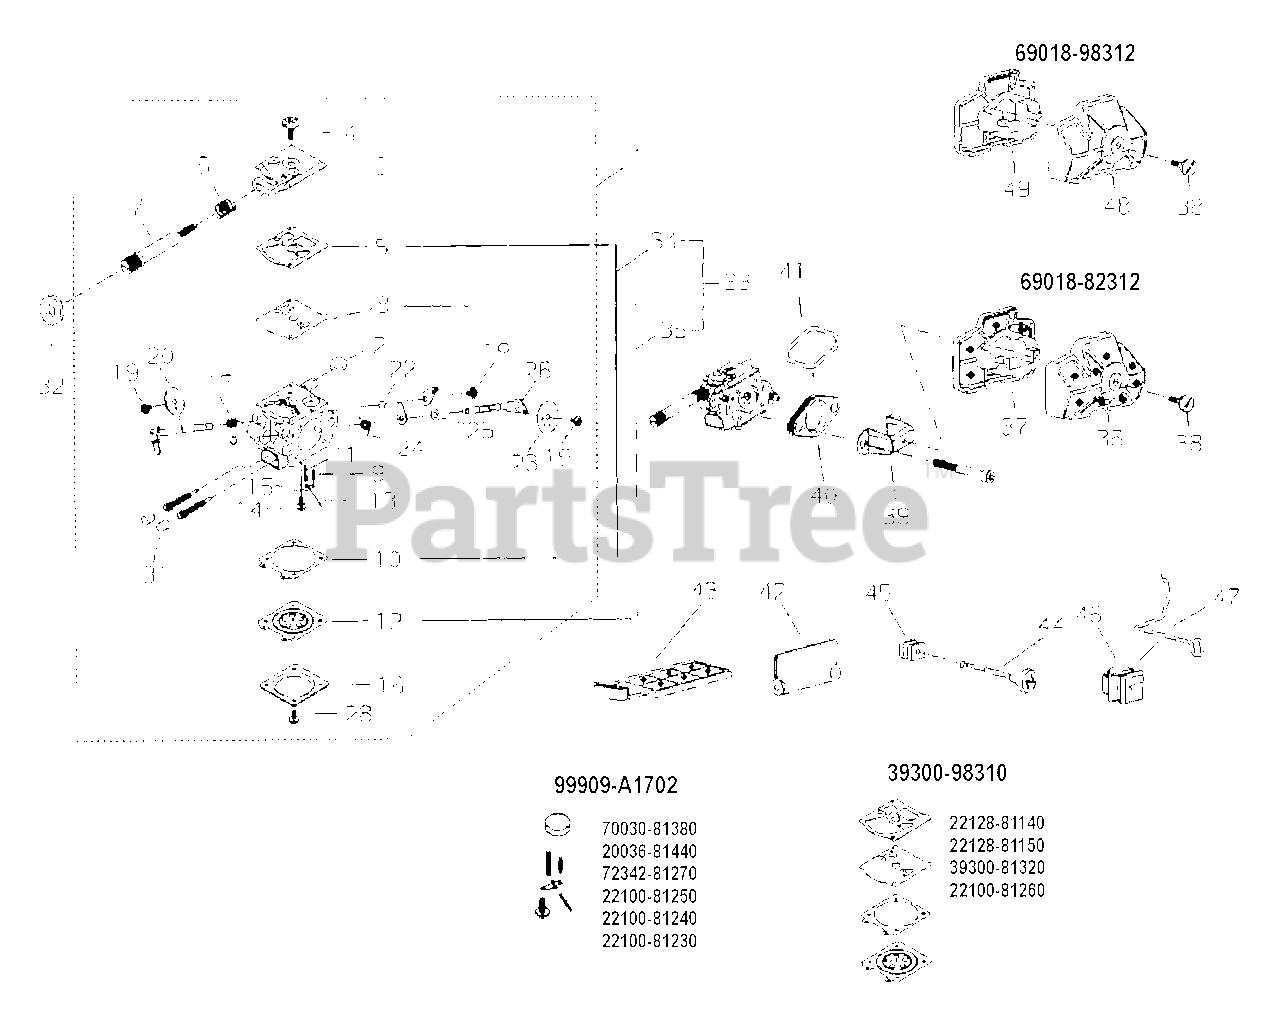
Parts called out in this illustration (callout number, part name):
1	CARBURETOR
2	STRAINER
3	COVER, PUMP
4	SCREW, PUMP COVER
5	GASKET, PUMP
6	SPRING
7	SCREW, IDLE ADJUST
8	DIAPHRAGM, PUMP
9	VALVE, INLET NEEDLE
10	GASKET
11	SPRING, METERING LEVER
12	DIAPHRAGM, METERING
13	PIN, METERING LEVER
14	SCREW, METERING LEVER PIN
15	LEVER, METERING
16	COVER, DIAPHRAGM
17	SPRING, RETURN
19	SCREW
20	VALVE, THROTTLE
22	RING, RETAINING
23	VALVE, CHOKE
24	SPRING, CHOKE RETURN
25	WASHER
26	SHAFT, CHOKE
28	SCREW
31	CAP, LIMITER
32	SEAL
33	DIAPHRAGM/GASKET KIT
34	GASKET KIT
35	DIAPHRAGM KIT
36	COVER, AIR FILTER
37	CASE, AIR FILTER
38	SCREW
39	BRACKET
40	BRACKET
41	O-RING
43	PRE-FILTER
44	SHAFT, CHOKE
45	GROMMET
46	GROMMET
47	ROD, THROTTLE
48	COVER, AIR FILTER
49	CASE, AIR FILTER
69018-82312	FILTER, AIR - MESH
69018-98312	FILTER, AIR - FLOCKED
99909-A1702	REPAIR KIT
